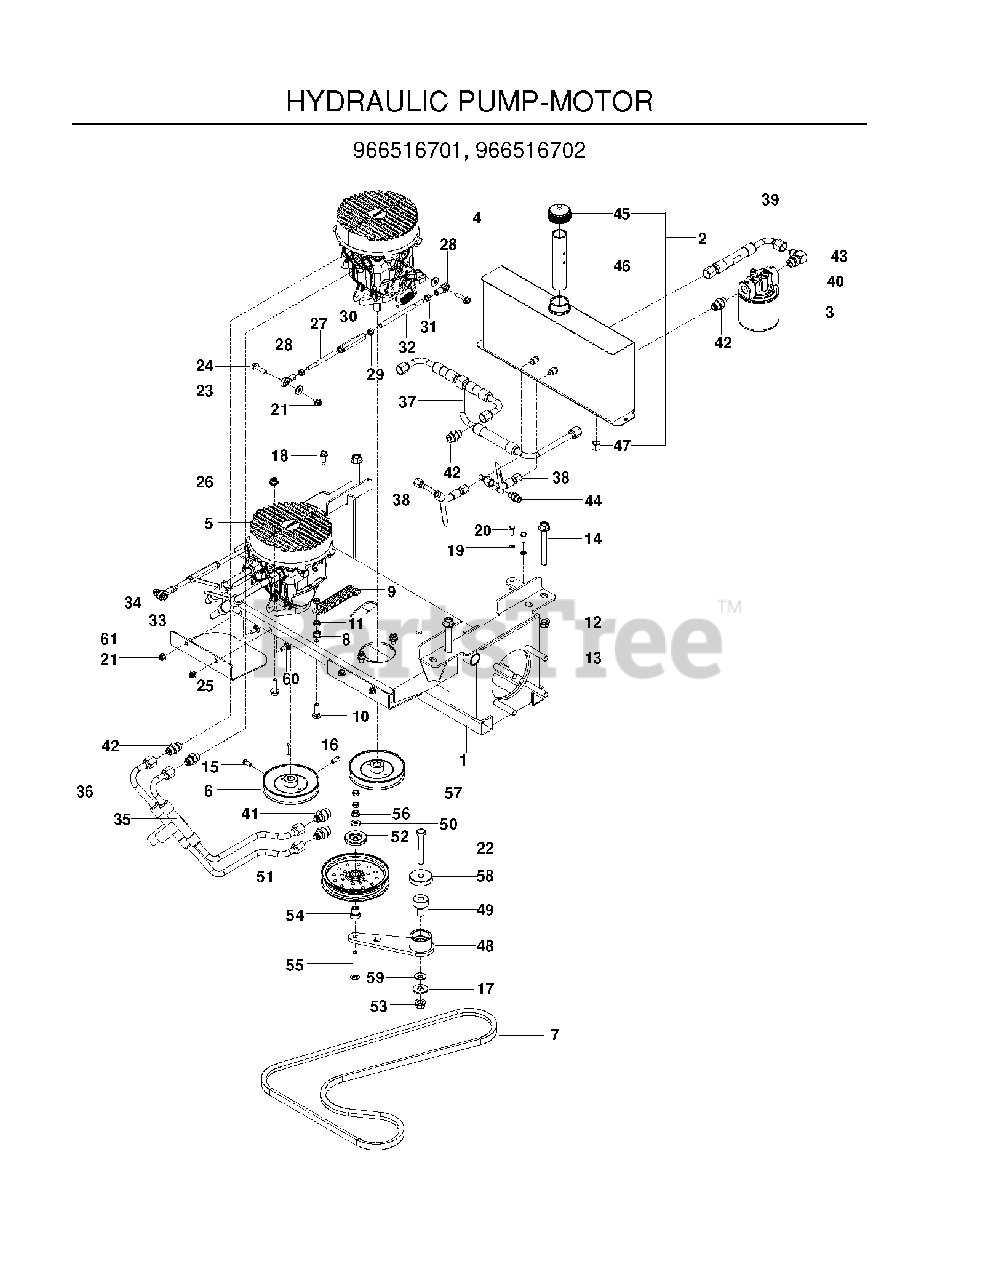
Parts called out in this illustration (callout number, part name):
1	FRAME, NYDR SUB, BLK
2	ASSEMBLY, OIL TANK
3	FILTER 25 MICRON
4	HG_PUMP, 16CC RT
5	HG_PUMP, 16CC LT
6	PULLEY, PUMP 17MM
7	BELT, "B", 75.5"
8	NUT 3/8C WHIZ
9	SPRING, PUMP
10	RHSNB 3/8-16 X 1-1/4
11	NUT HEX 3/8-16 NYLON, THIN
12	NUT, 1/2-13 HEX FLG NYLOC ZD
13	HCS 1/2C X 2 3/4
14	HHFS 1/2-13 X 4.0 GD8 ZD
15	SCREW 5/16C X 5/8 SQ HEAD
16	KEY 5 MM SQ X 25 MM
17	WASH USS FLAT 1/2
18	Hex Washer Head Bolt, 5/16-18 X 3/4 Thread Forming
19	LOCKWASHER 1/4"
20	HCS 1/4C X 3/4 HCS
21	5/16-18 NYLOC FLANGE NUT
22	HCS 1/2C X 3 1/4
23	WASHER 5/16 FLAT
24	HHFS 5/16-18 X 1.25 TPBLT GD 5
25	HHFS 3/8-16 X 1.25 GD 5
26	NUT 3/8-16 HEX FLG NYLOC ZD
27	LINKAGE, CONTROL, FT
28	BALL JOINT, RIGHT HANDED
29	NUT 3/8-24 JAM
30	TURNBUCKLE, 3/8
31	NUT 5/16F
32	LINKAGE, CONTROL, RR
33	LINE, RT A
34	LINE, RT B
35	LINE, LT A
36	LINE, LT B
37	LINE, CHARGE
38	LINE, CASE
39	LINE, SUCTION
40	FILTER HEAD
41	CONNECTOR, STRAIGHT
42	FITTING, STRAIGHT F6400-8-8-0
43	ELBOW, 90 DEGREE
44	STRAIGHT FITG
45	CAP, HYDRAULIC
46	TUBE, ANTI-SPLASH
47	NUT 9/16-18 JIC CAP
48	ARM, IDLER, STEEL, W/BGS
49	PIVOT, BEARING
50	WASHER, 3/8 THICK
51	IDLER, FLAT, 5.5"
52	DUST SHIELD
53	NUT, 1/2-13 HEX FLG NYLOC ZD
54	PIVOT, IDLER
55	RHSNB 3/8-16 X 2.75
56	NUT 3/8C WHIZ
57	NUT HEX 3/8-16 NYLON, THIN
58	SHIELD, DUST
59	CONTACT BELLSPR 1/2
60	BOLT 5/16C X 3/4" CARRIAGE
61	SHIELD, PULLEY, BLK
